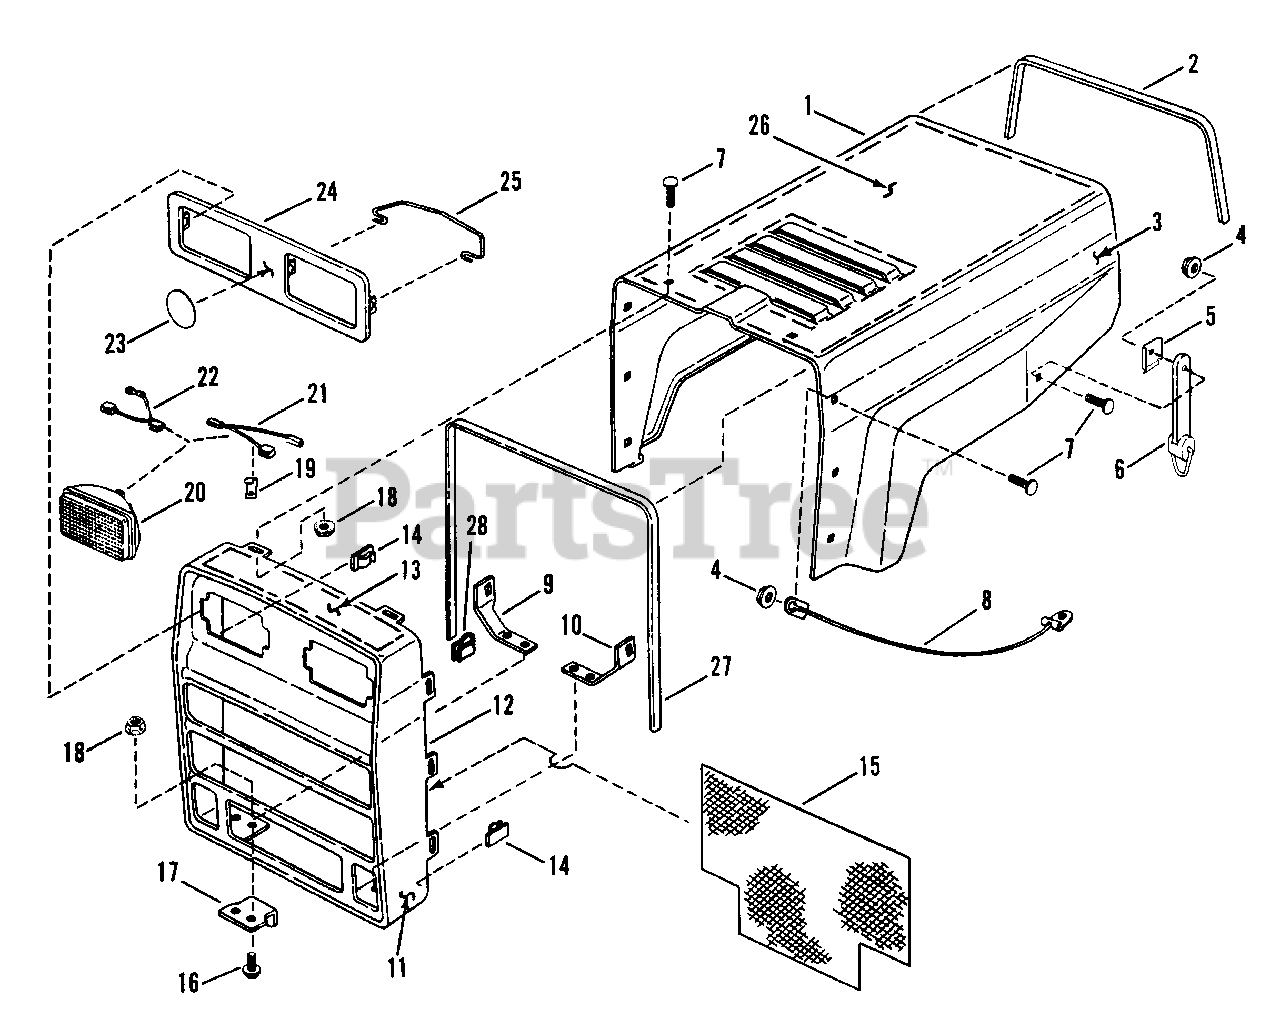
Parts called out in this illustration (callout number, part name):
1	HOOD, GT180H Tractor
2	TRIM, Hood
3	DECAL, Hood (L.H.)
4	NUT, 1/4-20 Hex Flange Top Thread Lock
5	CLIP, Hood Latch
6	LATCH, Hood Retaining
7	BOLT, 1/4-20 x 5/8" Flat Head Carriage
8	CABLE, Hood Stop
9	BRACE, Grill (R.H.)
10	BRACE, Grill (L.H.)
11	DECAL, Grill
12	GRILLE
13	HEAT SHIELD, Grill
14	CLIP
15	MESH, Grill
16	BOLT, 1/4-20 x 5/8" Hex Flange Lock
17	HINGE, Hood
18	NUT, 1/4-20 Hex Flange Lock
19	CLIP, Wiring Harness
20	HEADLAMP
21	HARNESS, Headlamp Wiring
22	HARNESS, Headlamp Ground Wiring
23	DECAL, Headlamp Bezel
24	BEZEL, Headlamp Mounting
25	RETAINER, Headlight
26	HEAT SHIELD, Hood
27	TRIM, Hood
28	U-CLIP
